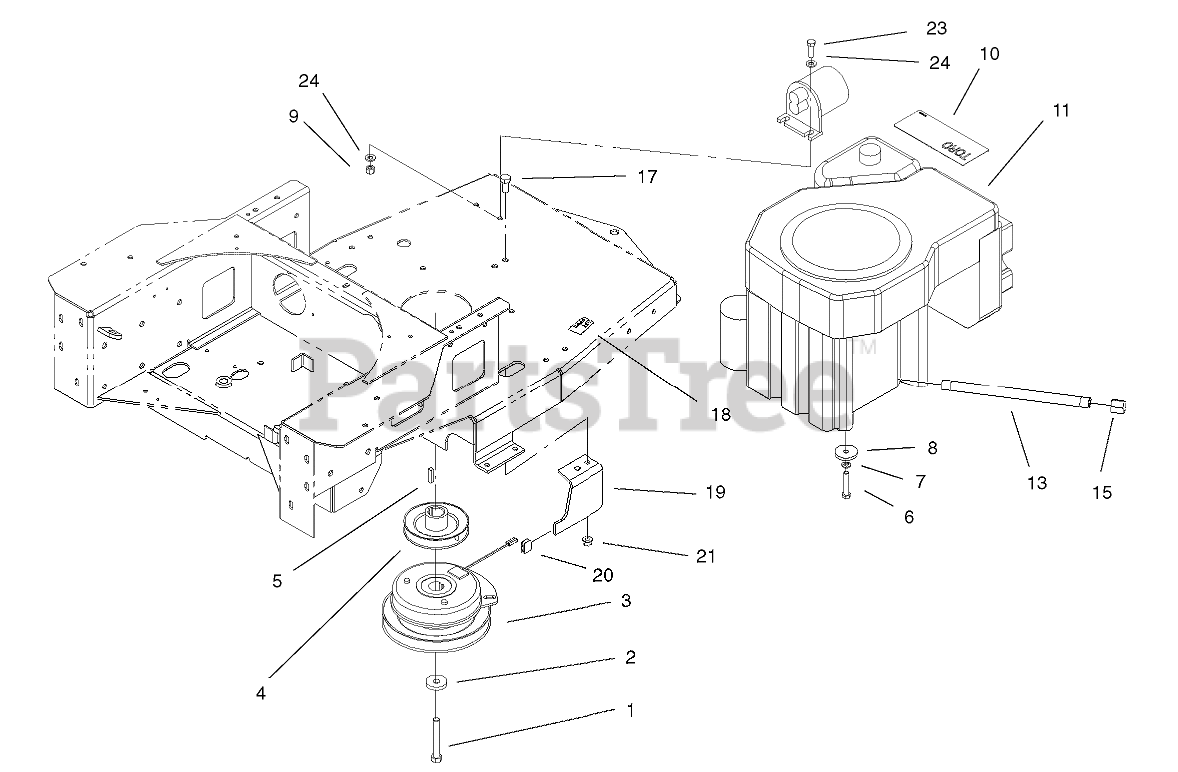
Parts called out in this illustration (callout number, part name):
1	SCREW-HH
2	WASHER
3	CLUTCH
4	PUMP DRIVE PULLEY ASM
6	SCREW-HH
7	WASHER-LOCK
8	SPACER-STEEL
10	Decal-Engine Kohler
13	NIPPLE-PIPE
15	CAP-PIPE
17	SCREW-HH
18	DECAL-SURFACE, HOT
19	STOP-CLUTCH
20	BUMPER
21	NUT-HF
